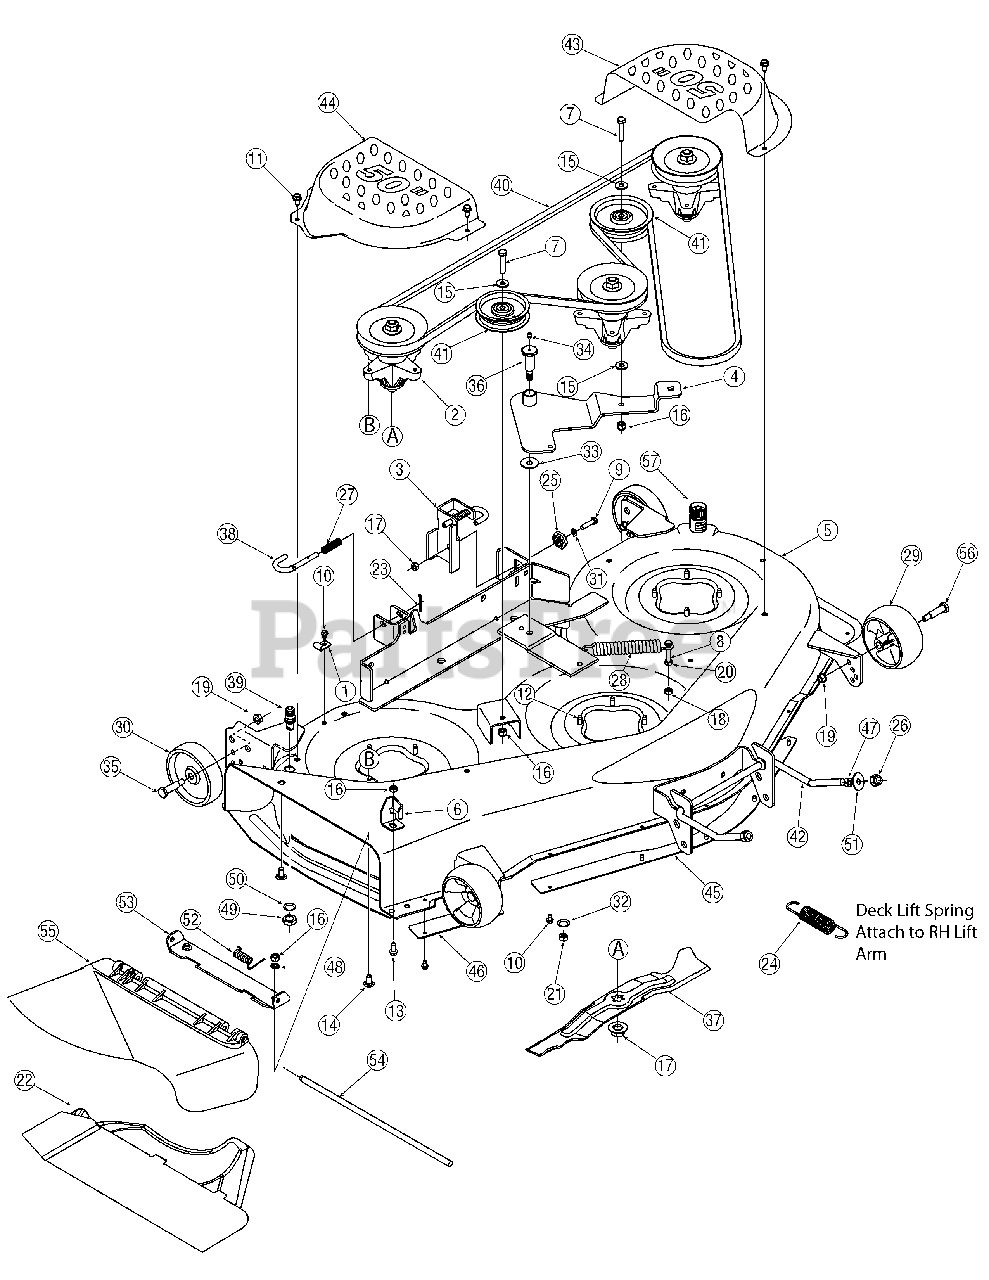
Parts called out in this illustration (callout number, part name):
1	Hook, Retainer
2	Spindle Assembly
7	Screw, 3/8-16, 1.75
8	Screw, 5/16-18 x 2.00
9	Screw, 5/16-18, 1.25, Gr5
10	Screw, 1/4-20 x 0.5
11	Screw, 5/16-18 x.500
12	Screw, 5/16-18 x.75
13	Hex Head Screw, 3/8-16 x 1.0
14	Screw, Carriage, 3/8-16 x.75
15	Washer, Flat,.406 x.875 x. .059
16	Nut, Nylon Lock, 3/8-16
17	Nut, Hex, Flange, 5/8-18
18	Nut, Nylon Lock, 5/16-18
19	Nut, Flange Lock, 3/8-16
20	Nut, Hex, 5/16-18, Gr5
21	Nut, 7/16-14
23	Pin, Cotter, 1/8 x 1.25
24	Extension Spring, 1.15 Dia.
25	Deck Adjustment Gear
26	Lock Nut, Hex, 1/2-13,
27	Spring, Compression,.531 x 1.75
28	Spring, Extension,.94 x 6.74
29	Deck Wheel, 5.0
30	Deck Wheel, 5.0
31	Washer, Lock, 5/16, Regular
32	Washer, Bell,.45 x 1.0 x. .062
33	Washer, Flat,.442 x 1.38 x .060
34	Fitting, Lube, 3/16
35	Shoulder Screw 3/8-16
36	Screw, Shoulder,.68 x 1.59
37	Blade
38	Rod, Handle, Deck Release
39	Deck Water Nozzle
40	Belt, V-Type, Aramid
41	Pulley, Idler, 3.5"
42	Rod, Deck Adjustment
47	Hex Nut, 1/2-13
48	Push Nut, 3/8
49	Hex Nut, M16-1.5
51	Flat Washer,.51 x 1.12 x. .06
52	Torsion Spring,.44ID x 2.10
53	Chute Bracket
55	Chute Deflector
55	Chute Assembly (Incl. Ref.# 52-55)
56	Shoulder Screw 1/2 x 2.5
57	Water Nozzle Adapter
